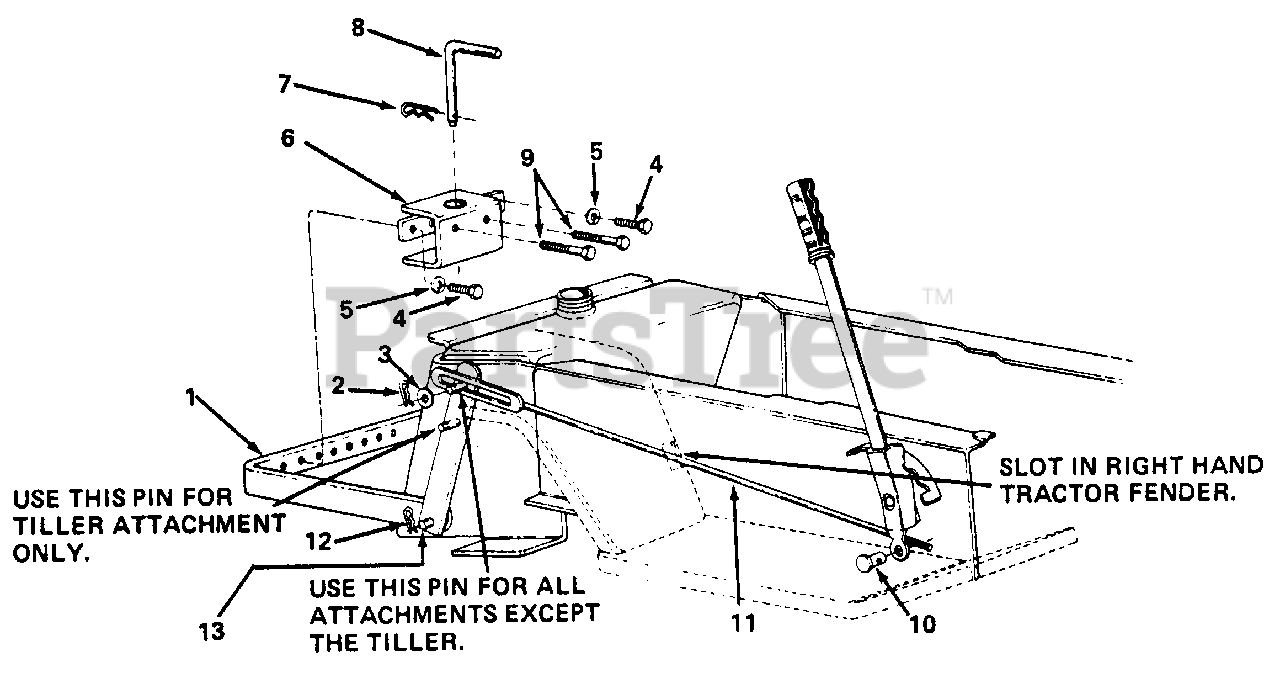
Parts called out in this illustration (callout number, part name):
3	Fl.-Wash. 1/2" I.D.
4	Hex Scr. 1/2-13 x 1.00" Lg.
5	L.-Wash. 1/2" Scr.
8	Hitch Pin
9	Hex Scr. 1/2-13 x 3.00" Lg.
10	Adjustment Ferrule
13	Hitch Rod
